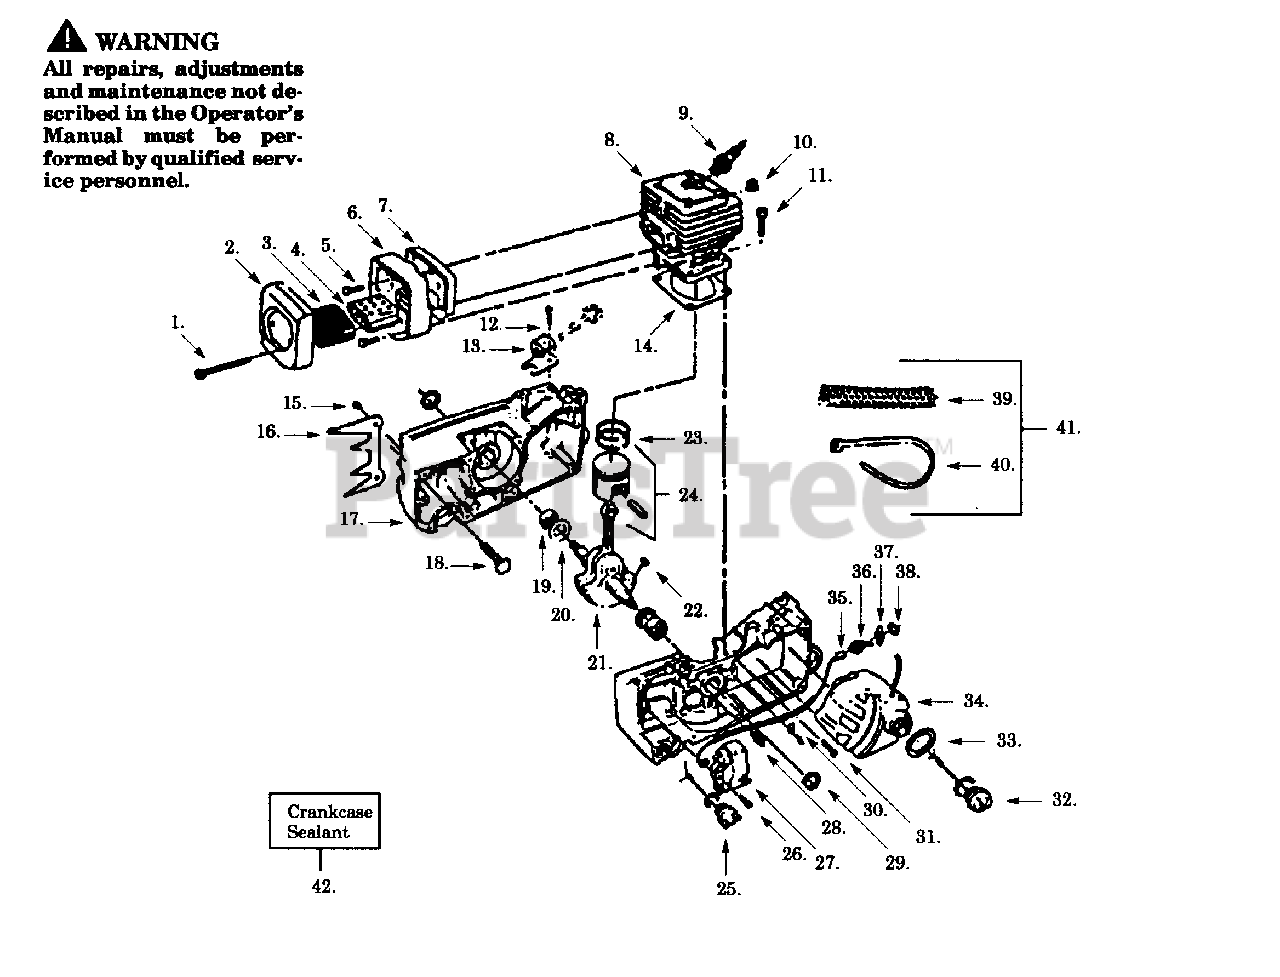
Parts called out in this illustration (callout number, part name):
2	Muffler Cover
3	Spark Arrestor
4	Muffler Diffuser
6	Muffler Body
7	Muffler Back Plate
8	Model 375
8	Model 385,395
9	Spark Plug
10	Clip-High Tension Lead
13	Bracket & Bushing Ass'y.
14	Cylinder Gasket
17	Crankcase Ass'y. (Inc.18,25,35, & Oil Cap Ass'y. from "External Power Unit.
18	Bar Stud Replacement Kit (5/16")
19	Crankshaft Bearing
21	Crankshaft Ass'y.
22	Flywheel Key
23	Model 375
23	Model 385,395
24	Model 375
24	Model 385,395
25	Oil Cap Ass'y.
27	Ignition Module
29	Crankshaft Seal
30	Module Lead Clamp
32	Fuel Cap Ass'y.
33	Fuel Tank Neck Seal
34	Fuel Tank Ass'y.
36	Toggle Switch
37	Ignition Switch Plate
38	Nut
39	Winter Screen
40	Tie Strap
41	Winter Kit (Inc. 39,40)
42	Crankcase Sealant
43	Model 375
43	Model 385,395
44	Bow Guide Manual
45	Model 375 Carton (Not a serviceable part)
45	Model 385,395 Carton (Not a serviceable part)
